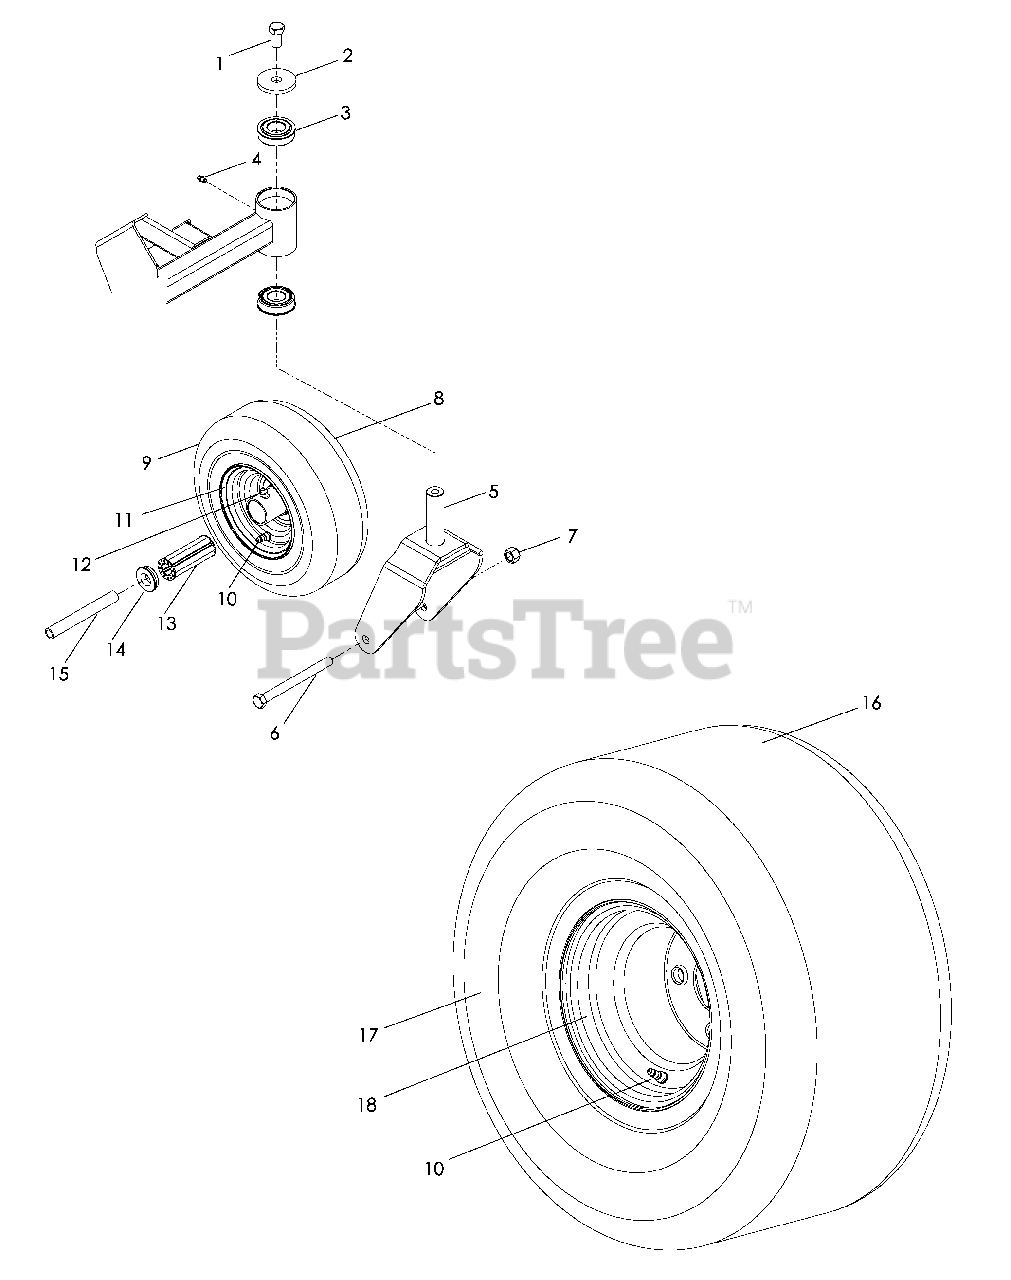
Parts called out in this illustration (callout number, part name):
1	HCS ½-13 x 1
2	HEAVY WASHER
3	BEARING, FLANGED
5	CASTER YOKE
6	HCS ½-13 x 5½
7	NUT ½-13 NYLOC
8	CASTER TIRE, COMPLETE Items 8-14
9	TIRE, 4 PLY, 410/350-5
10	VALVE STEM
12	ZERK
13	ROLLER BEARING 3¼
14	BEARING, FLANGED
17	TIRE & RIM, REAR MODEL EZ4220
